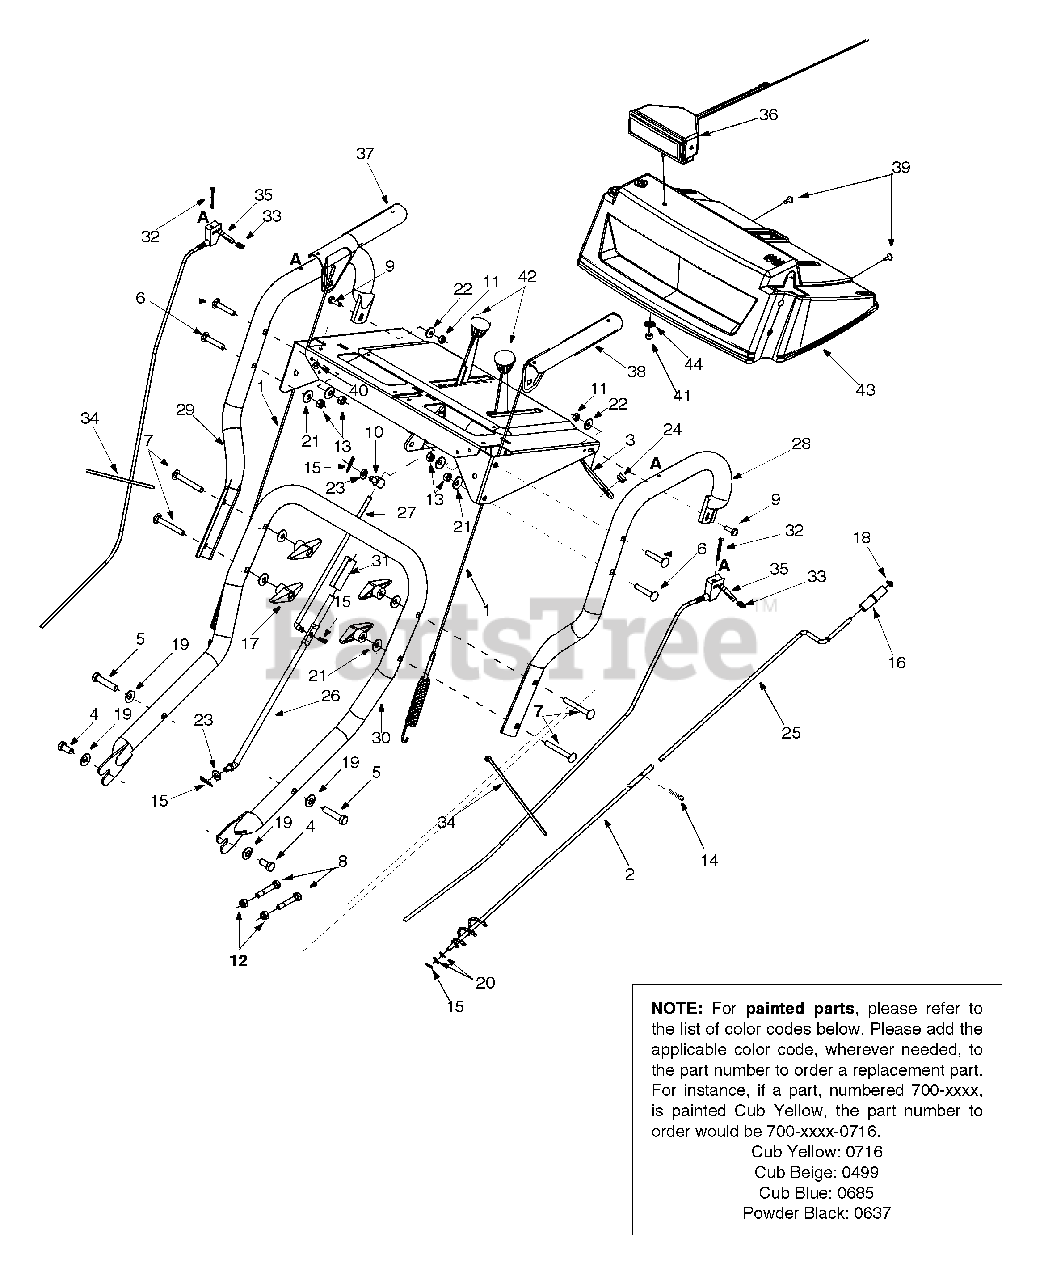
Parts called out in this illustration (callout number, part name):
1	Cable Assembly: Auger/Drive
4	Hex Screw 3/8-16 x .75"
5	Hex Screw 3/8-16 x 1.75"
6	Carriage Bolt 5/16-18 x 1.75"
7	Carriage Bolt 5/16-18 x 2.5"
8	Shear Bolt 5/16-18 x 1.75"
9	Hex Screw 1/4-20 x .75"
10	Ferrule
11	Hex Nut 1/4-20
12	Hex Lock Nut
14	Hairpin Clip
15	Hairpin Clip
16	Chute Crank Knob
19	Bell Washer
20	Flat Washer
21	Beleville Washer
22	Bell Washer
23	Flat Washer
24	Plastic Bushing
26	Lower Shift Rod
27	Upper Shift Rod
31	Clutch Rod Connector
32	Oval C-Sunk Screw
33	Flat Weld Nut
34	Cable Tie
35	Trigger Control
36	Light Assembly
37	Handle Engagement RH
38	Handle Engagement LH
39	Special B Screw
40	Hex Sems Nut
41	Hex Lock Nut
42	Shift Knob
43	Handle Panel
44	5/16 Washer
